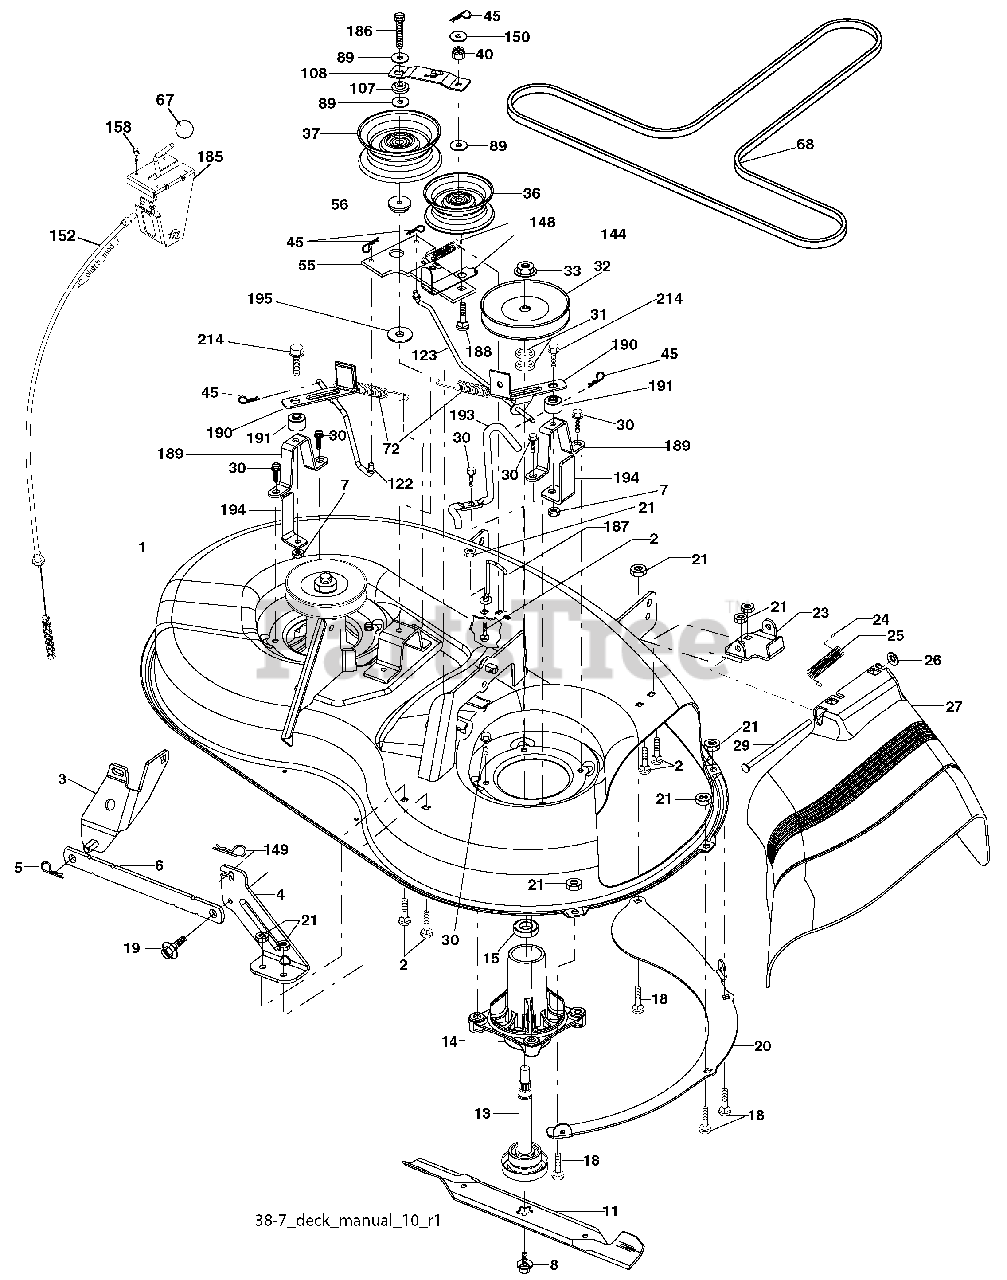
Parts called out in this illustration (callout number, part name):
1	Mower Housing Assembly
2	Bolt Carriage 5/16-18 x 3/4
3	Bracket Asm Fr. Sway Bar
4	Bracket Deck Sway Bar 38"/42"
5	Retainer Spring
6	Bar Sway Deck
7	Nut Lock 5/16-18 unc
8	Bolt 3/8-24 x 1.25 Gr. 8
11	Blade, 38" Hi-Lift (For bagging or discharge)
11	Blade, 38", Mulching (For mulching or discharge)
13	Shaft Assembly, Mandrel, Vented
14	Housing, Mandrel, Vented
15	Bearing, Ball, Mandrel
18	Blade Rdhd Sqnk 5/16-18 x 5/8
19	Bolt, Shoulder
20	Baffle Vortex Front
21	Nut
23	Bracket, Mower Deflector
24	Cap, Sleeve
25	Spring, Torsion, Deflector
26	Nut, Push
27	Shield, Deflector
29	Rod, Hinge
30	Screw Thdrol.
31	Washer, Spacer
32	Pulley, Mandrel
33	Nut, Toplock
36	Pulley, Idler, Flat
37	Pulley, Idler Flat
40	Nut, Crownlock 3/8-16 unc
45	Retainer
55	Idler Arm Assembly
56	Spacer, Retainer
67	Knob
68	V-Belt
72	Spring Brake Return
89	Washer 13/32 x 13/16 x 11 Ga.
107	Spacer Retainer
108	Stiffener, Idler Arm
122	Rod, Brake LH
123	Rod, Brake RH
144	Keeper Belt Idler Tension
148	Spring Return Idler
149	Retainer Spring Yellow
150	Washer 9/32 x 3/4 x 10 Ga.
152	Clutch Cable 38"
158	Screw Hex Thd Cut 1/4-20 x 1/2
185	Head Asm Cable Clutch
186	Screw Hex Wsh Thdrol 3/8-16 x 2-3/4
187	Keeper Belt M Shape
188	Bolt Carriage Idler
189	Brake Stand
190	Brake Arm
191	Brake Spacer
193	Keeper Belt Rh Mandrel
194	Brake Guard
195	Washer 13/32 x 2 x 10 Ga.
214	Bolt/Washer Asm. 5/16-18
214	Brake Assembly
214	Mandrel Assembly
214	Replacement Mower, Complete
